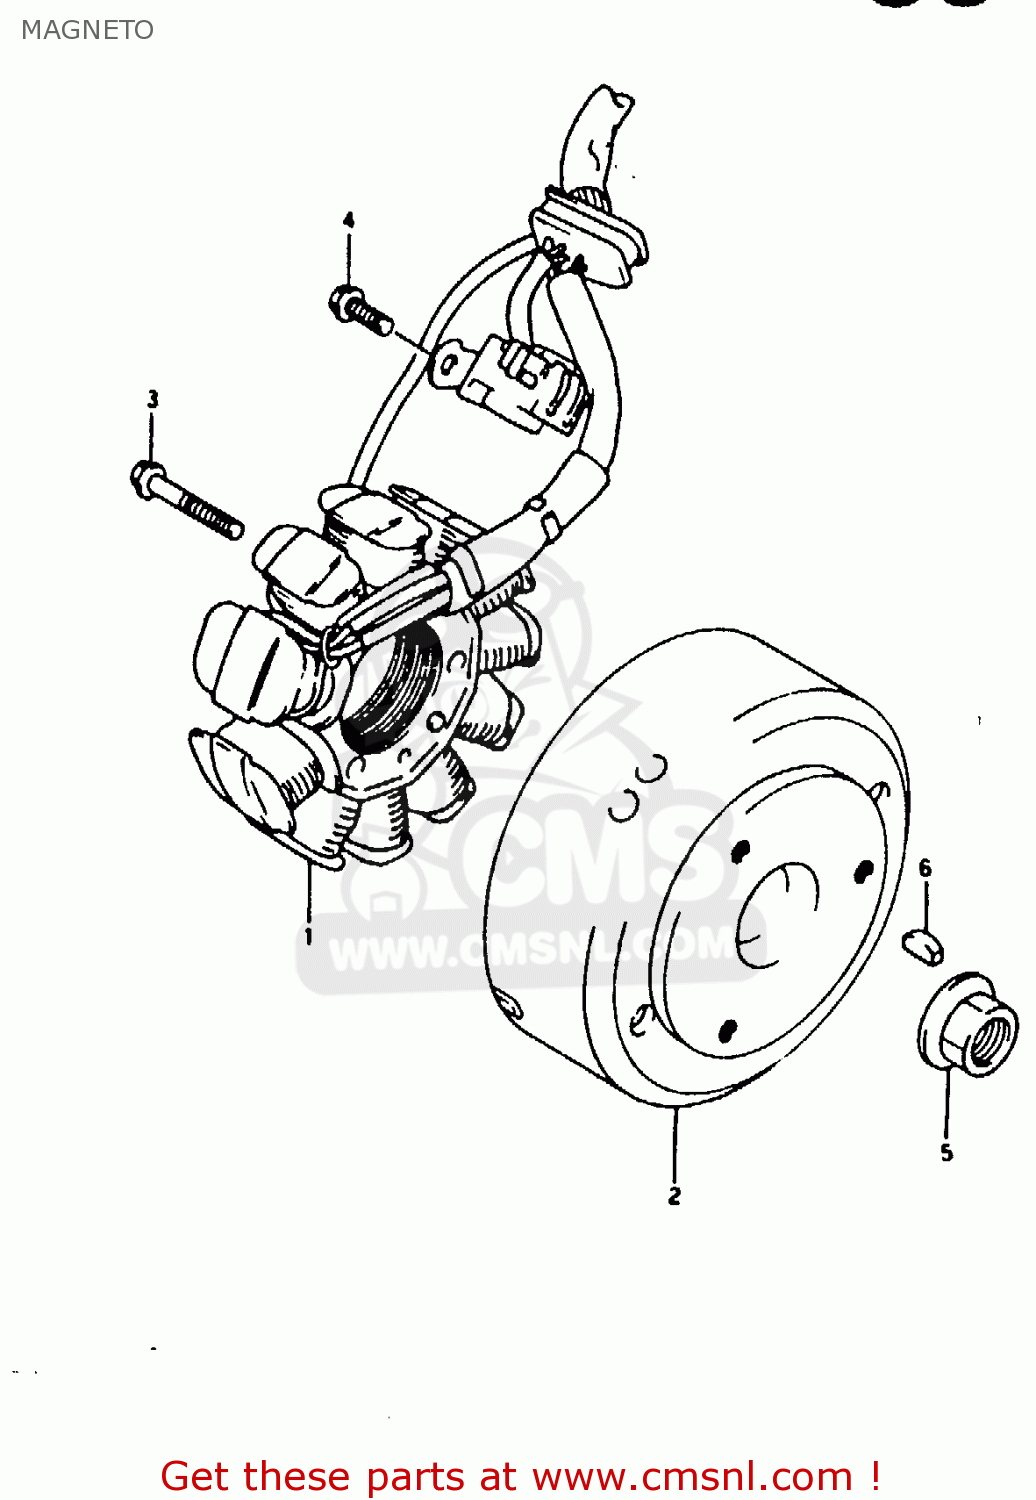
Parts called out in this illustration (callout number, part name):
1	STARTER ASSY
2	ROTOR, FLYWHEEL
3	BOLT
4	BOLT
5	NUT
6	KEY
